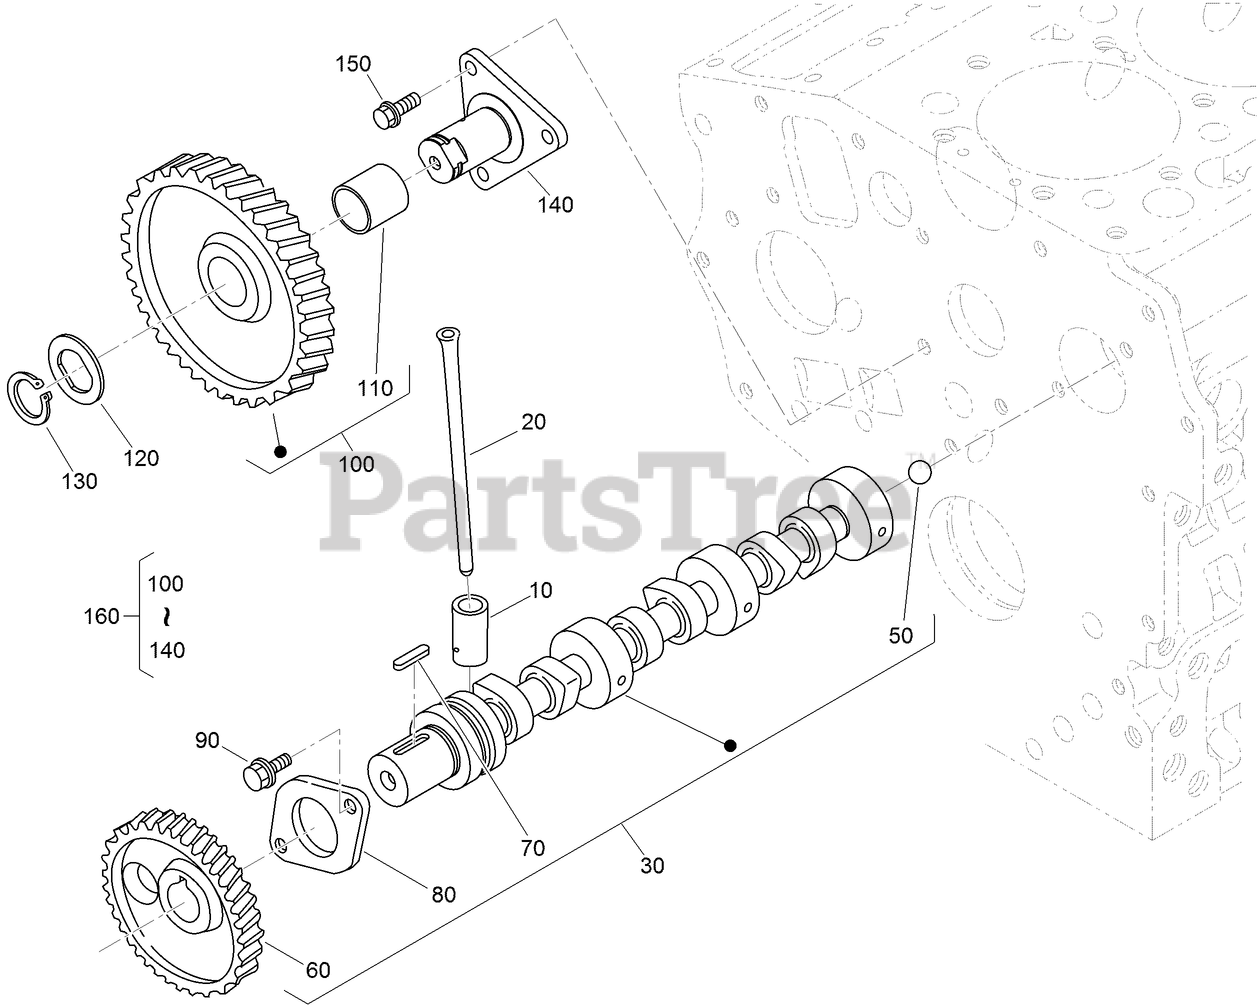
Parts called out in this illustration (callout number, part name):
10	TAPPET
20	ROD-PUSH
30	CAMSHAFT ASM
60	GEAR-CAM
70	KEY-FEATHER
80	STOPPER-CAMSHAFT
100	IDLE GEAR ASM
110	BUSHING
120	COLLAR-GEAR, IDLE
130	RING-SNAP
140	SHAFT-GEAR, IDLE
150	BOLT-FLANGE
160	IDLE GEAR ASM
